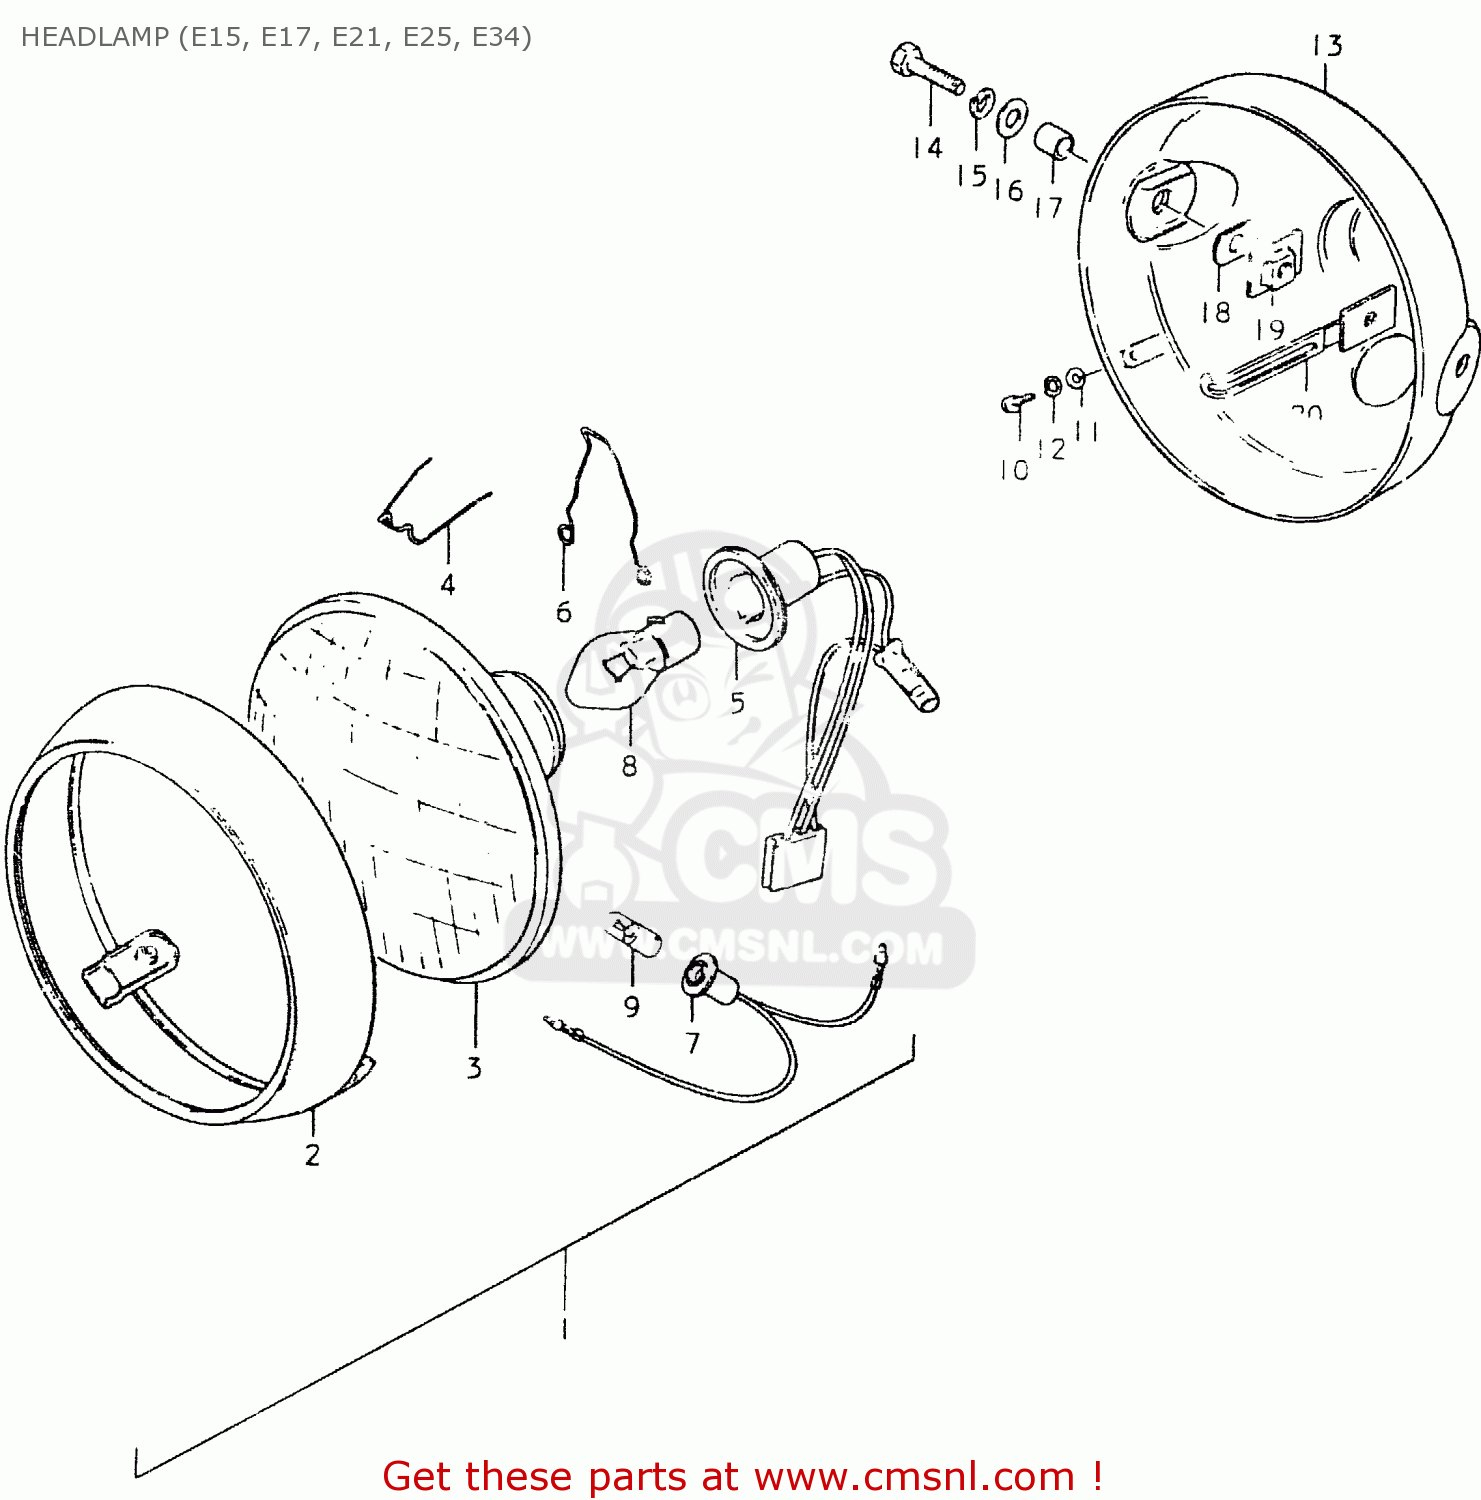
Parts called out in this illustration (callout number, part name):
1	HEADLAMP ASSY
2	RIM
3	UNIT
4	SPRING
5	SOCKET
6	CLAMP,HEADLAMP
7	SOCKET
8	BULB (6V,35/35W)
9	BULB (6V,4W)
10	SCREW
11	WASHER
12	LOCK WASHER
13	HOUSING,HEADLAMP
14	BOLT
15	LOCK WASHER
16	WASHER
17	SPACER (8.8X12X7)
18	CUSHION
19	PLATE,HEADLAMP HOUSING
20	PLATE,HEADLAMP HOUSING
